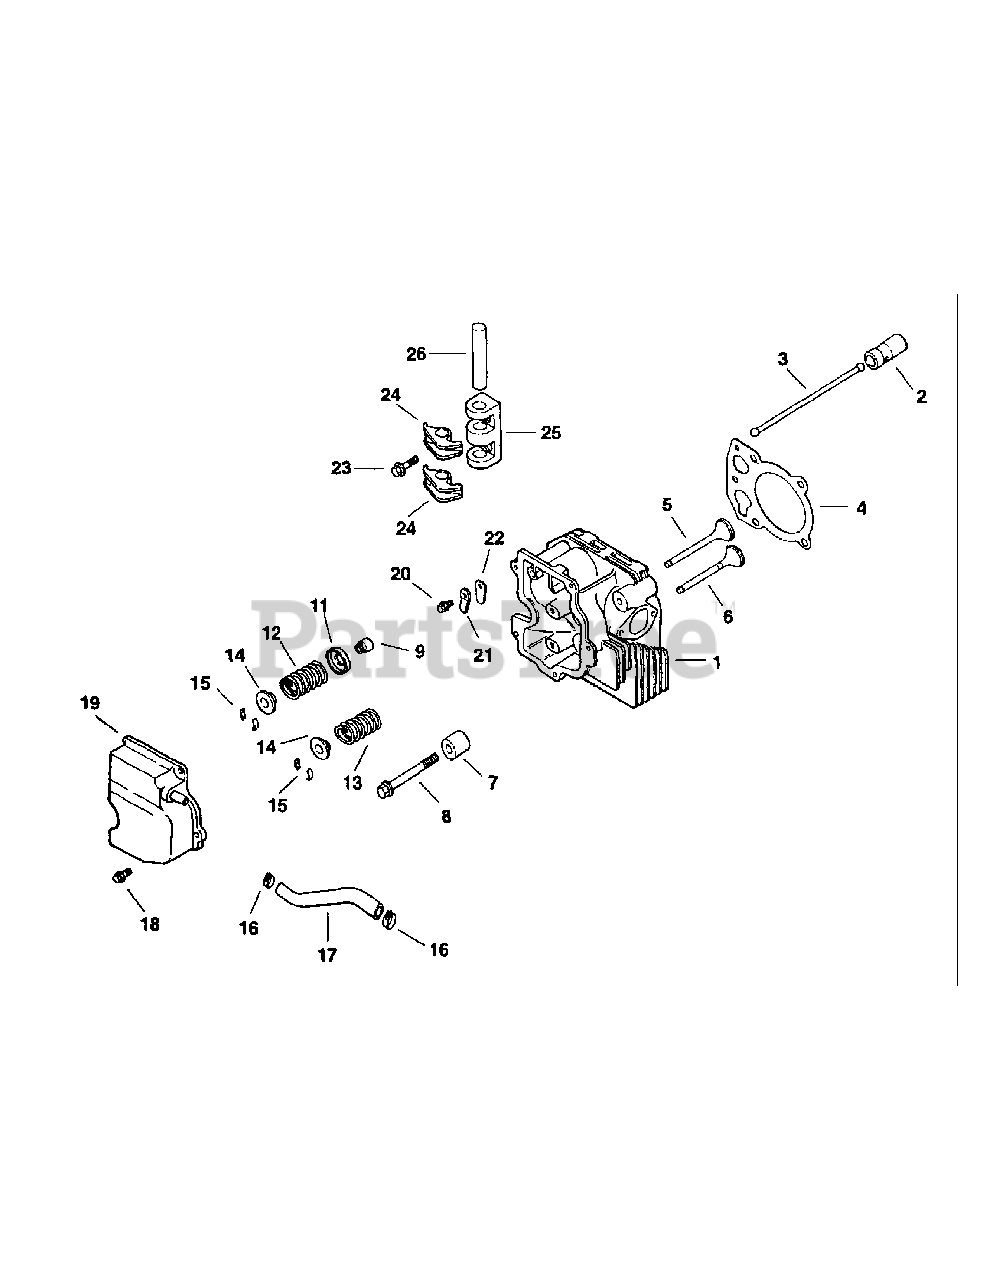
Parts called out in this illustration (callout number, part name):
1	Head, Cylinder
2	Lifter, Valve
3	Rod, Push
4	Gasket, Cylinder Head
5	Valve, Intake (Std.)
5	Valve, intake (.25 o.s.)
6	Valve, Exhaust (Std.)
6	Valve, Exhaust (.25 o.s.)
7	Spacer, Head Bolt Exhaust Port
8	Screw, Hex Flange
9	Seal, Valve Stem
11	Spring, Retainer
12	Spring, Intake Valve
13	Spring, Exhaust Valve
14	Cap, Valve Spring
15	Retainer Kit
16	Clamp, Hose
17	Hose, Breather
18	Screw, Hex Flange
19	Cover, Valve w/Nipple
20	Screw, Hex Flange
21	Retainer, Breather Reed
22	Reed, Breather
23	Screw, Hex Flange
24	Arm, Rocker
25	Bridge, Rocker Arm
26	Shaft, Rocker Arm
